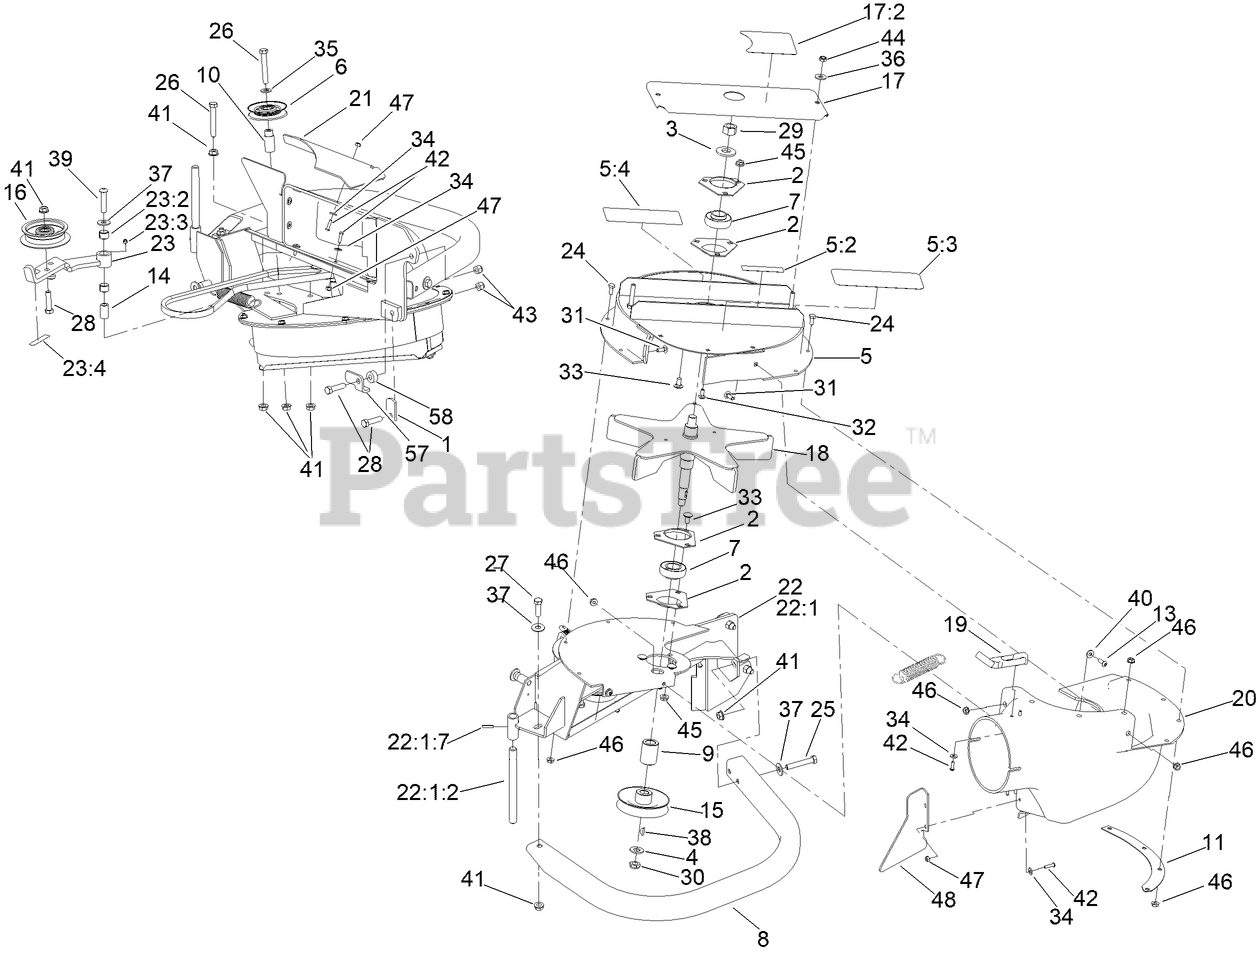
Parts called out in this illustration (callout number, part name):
1	LATCH-CATCHER, GRASS
2	HOUSING-FLANGE
3	WASHER-SPRING
4	WASHER-FLAT
5	HOUSING W/DECAL-UPPER
5:2	DECAL - VIB, PINCH WARNING
5:4	DECAL-WARNING
6	IDLER-INSIDE
7	BEARING
9	SPACER
11	PLATE-BACKING, BLOWER
13	SCREW-HSBH
14	BUSHING-PIVOT, IDLER
15	PULLEY
16	IDLER-FLAT
17	COVER-BEARING, W/DECAL
17:2	DECAL-WARNING
18	IMPELLER
19	LATCH-RUBBER
20	CHUTE-BLOWER, SMALL
21	PLATE-BOTTOM
22	BLOWER MOUNT ASM
22:1	BLOWER-MOUNT
22:1:2	SHAFT-CATCHER, GRASS
22:1:7	PIN-ROLL
23	IDLER ARM ASM W/BUSHINGS
23:2	BUSHING
23:3	FITTING-GREASE
23:4	DECAL-WARNING
24	SCREW-HH
25	SCREW-HH
26	SCREW-HH
27	SCREW-HH
28	SCREW-HH
29	NUT-HEX
30	NUT-LOCK, NI
31	BOLT-CARR
32	SCREW-CARR
33	SCREW-CARR
34	WASHER-FLAT
35	WASHER-FLAT
36	WASHER-FLAT
37	WASHER-FLAT
38	KEY-WOODRUFF
39	SCREW-HSBH
40	WASHER-FLAT
41	NUT-HHF, WHIZ
42	SCREW-HSBH
43	NUT-LOCK, NI
44	NUT-LOCK, NI
45	NUT-HF
46	NUT-HF
47	NUT-LOCK, NI
48	PLATE-FILLER, REAR
57	LATCH-STOP
58	SPACER
